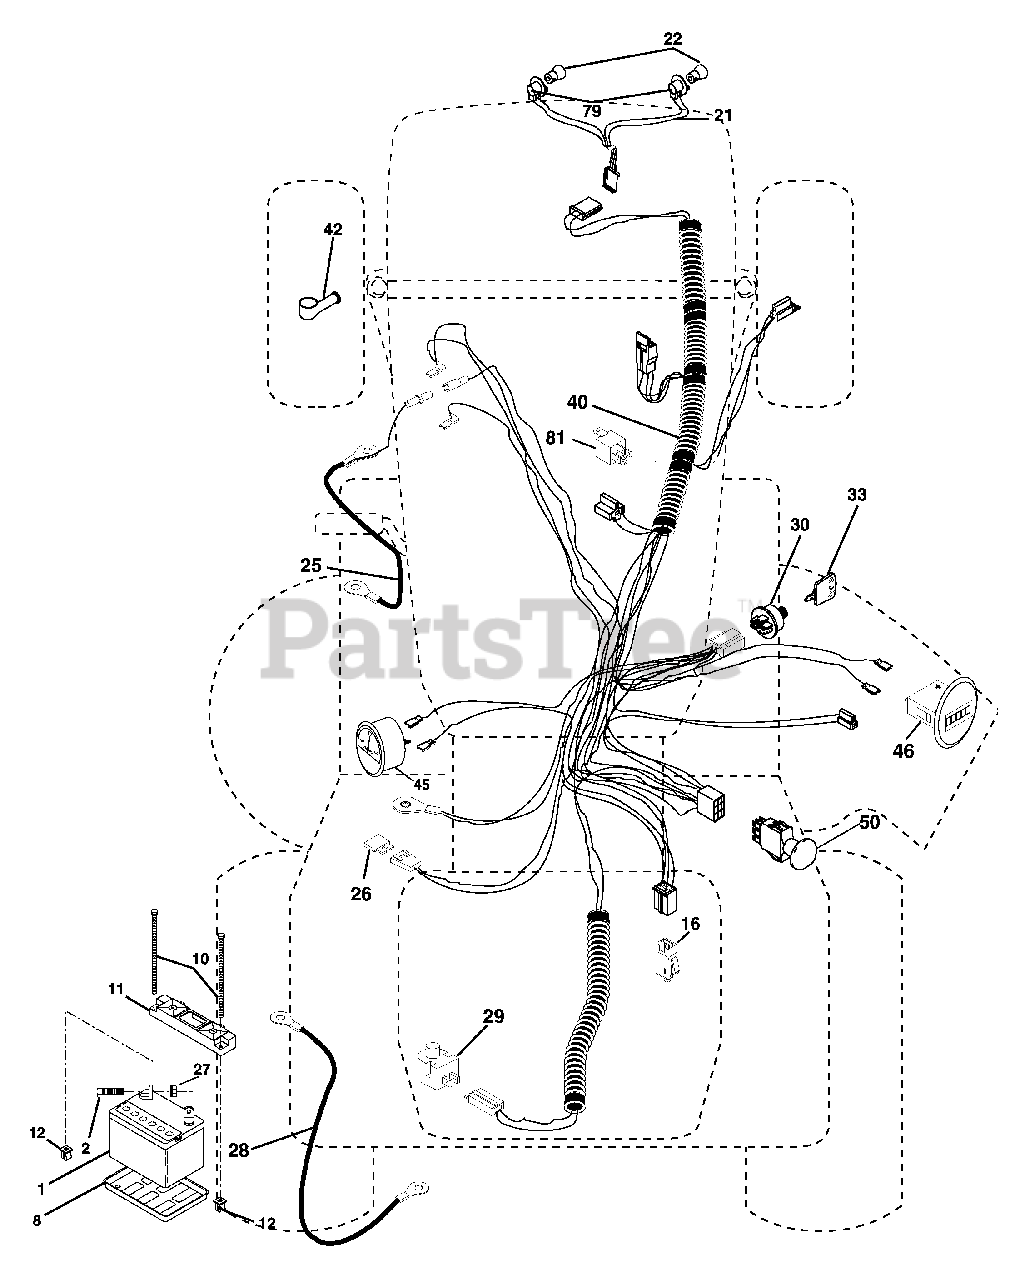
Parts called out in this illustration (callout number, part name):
1	Battery
2	Bolt Hex Head 1/4-20 x 3/4
8	Tray, Battery
10	Bolt, Battery Front 1/4-20 x 7.5 Zinc
11	Holddown Battery Front Mount
12	Nut, Push Nylon 1.4" Battery Front
16	Switch Interlock Push-In
21	Harness Socket Light w/4152J
25	Cable, Battery
27	Nut Keps Hex 1/4-20
28	Cable, Ground
29	Switch, Plunger NC Gray
30	Switch, Ign
40	Harness Ign.
42	Cover, Terminal Red
50	Switch, PTO
79	Socket Assembly Bulb
81	Relay Asm.
